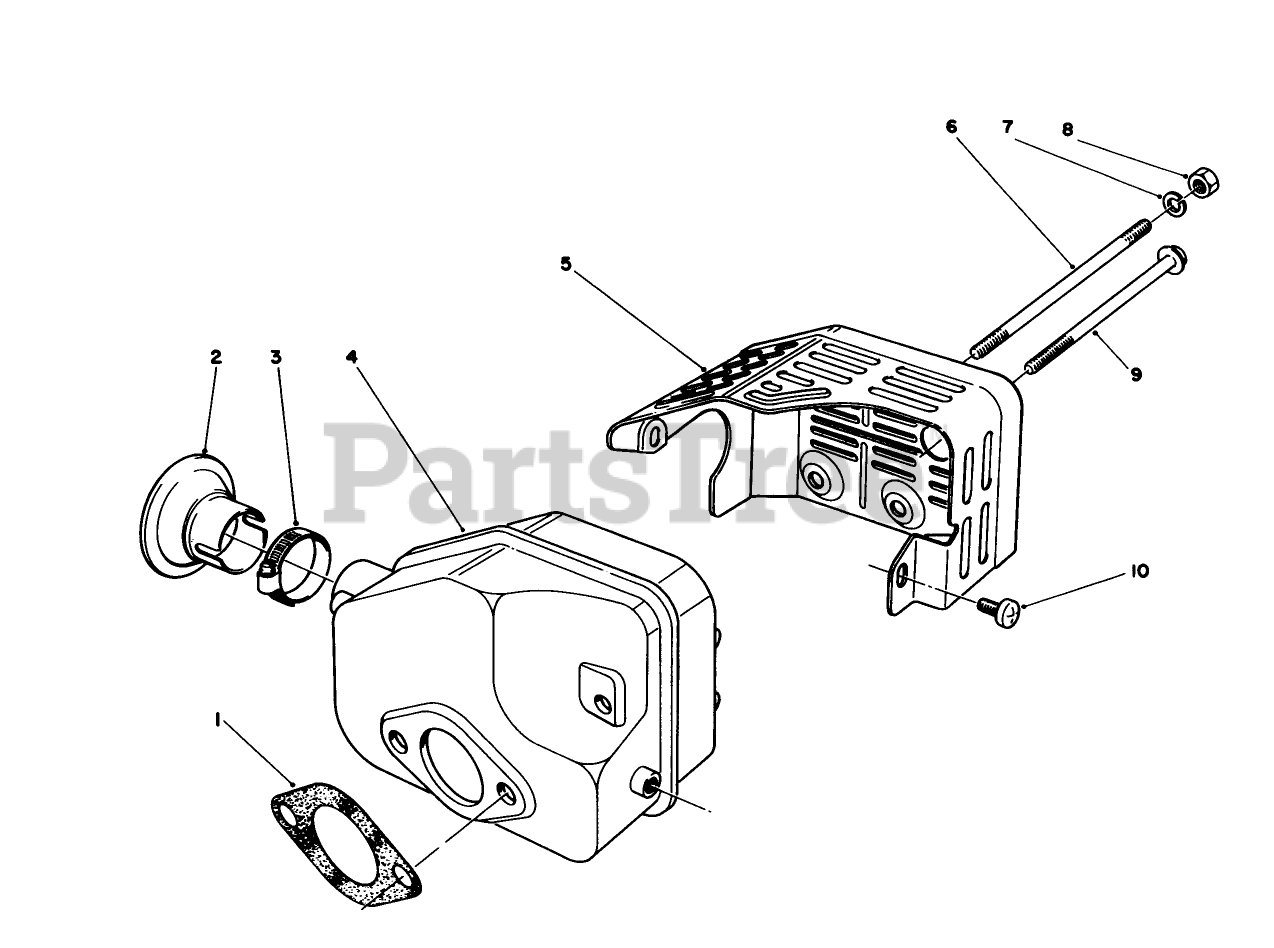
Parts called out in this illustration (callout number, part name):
1	GASKET
3	Clamp
4	MUFFLER
5	COVER-MUFFLER
7	WASHER-LOCK
10	SCREW
